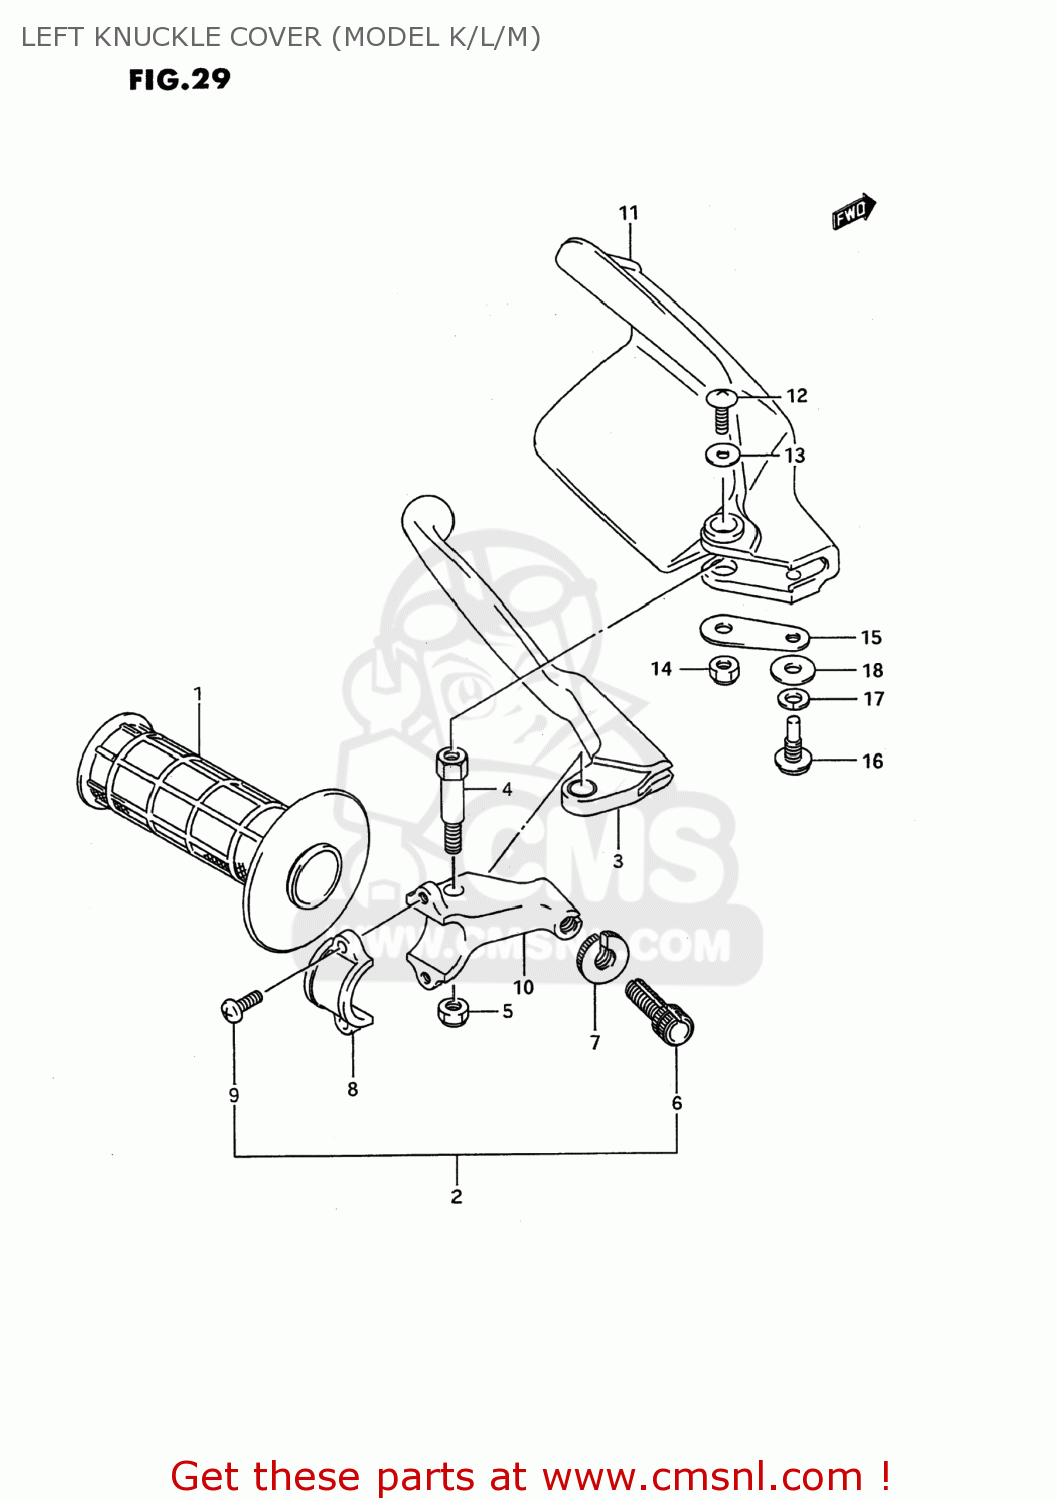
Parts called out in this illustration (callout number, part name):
1	GRIP,L
2	LEVER ASSY,CLUTCH
3	LEVER,CLUTCH
4	BOLT,LEVER SET
5	NUT 6MM
6	ADJUSTER,CABLE
7	NUT,LOCK
8	BRACKET,CLUTCH LEVER HOLDER
9	SCREW(5X14)
10	HOLDER,CLUTCH LEVER
11	COVER,KNUCKLE,LEFT
12	SCREW(5X10)
13	WASHER (5.5X16X1.2)
14	NUT 6MM
15	PLATE,KNUCKLE COVER,L LWR
16	SCREW
17	WASHER,LOCK
18	WASHER (6.5X17X1.6)
